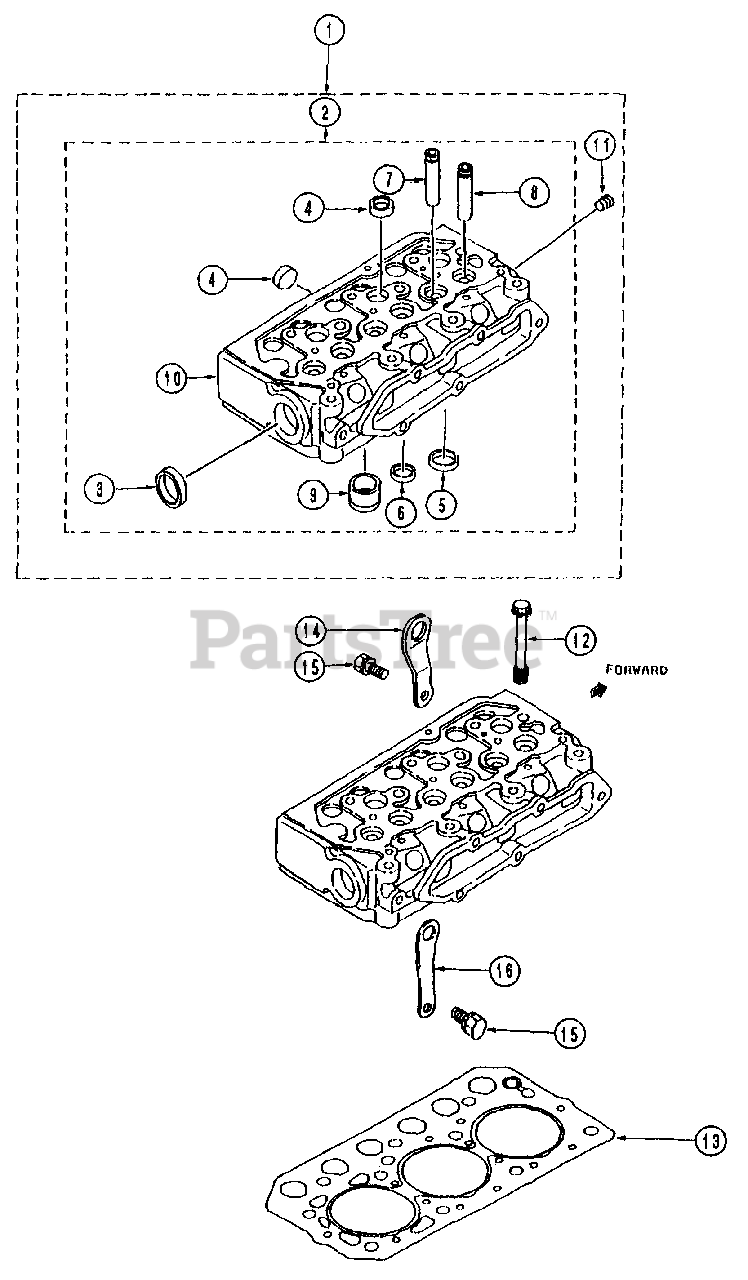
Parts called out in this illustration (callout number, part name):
1	Head Ass'y, Cylinder
2	Head Sub Ass'y, Cyl.
3	Cap, Sealing
4	Cap, Sealing
5	Seat, Valve, In.
6	Seat, Valve, Ex.
7	Guide, Exhaust Valve
8	Guide, Inlet Valve
9	Jet, Combustion
10	Cyl. Head Ass'y
11	Plug, Taper
12	Bolt, Cylinder Head
13	Gasket, Cylinder Head
14	Hanger, Engine
15	Bolt, W/Washer
16	Hanger, Engine
